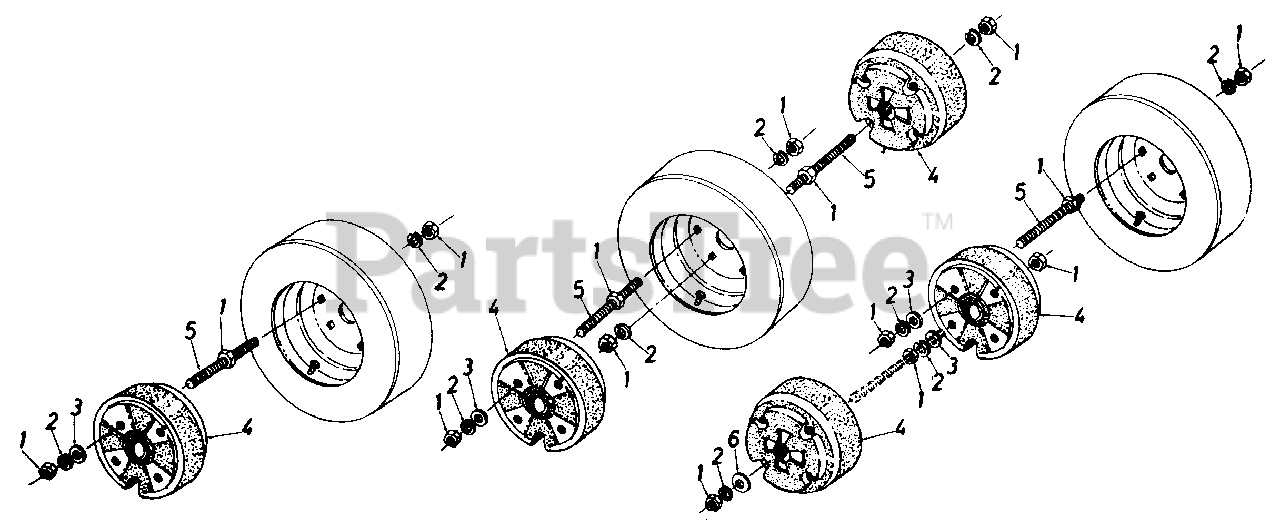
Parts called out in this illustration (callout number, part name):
1	Hex Nut 1/2-13 Thd.
2	Lock Washer 1/2" I.D.
3	Flat Washer .53" I.D. x .93" O.D.
4	Wheel Weight
5	Rod Threaded 1/2-13 x 9.50 Lg.
6	Fl.-Wash. .50" I.D. x 2.00" O. D.
